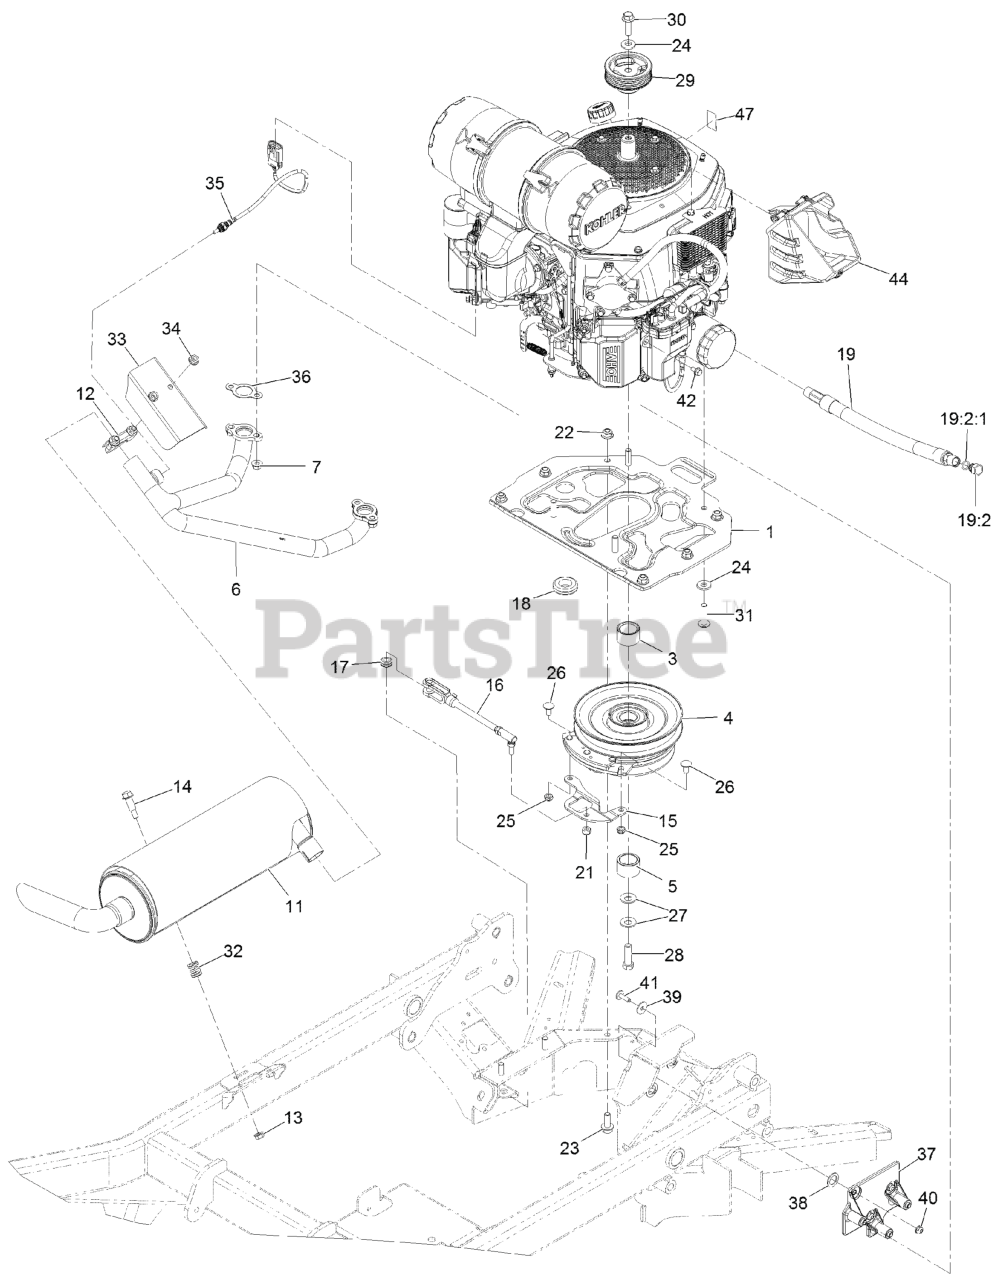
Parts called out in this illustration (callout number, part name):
1	PLATE, ENGINE
3	SPACER, CLUTCH
5	SPACER, CLUTCH
6	HEADER, KOHLER
7	NUT-FLANGE
12	CLAMP-MUFFLER
14	Bolt-Shoulder
15	STRAP, CLUTCH
16	ASM, CLUTCH ANCHOR
17	GROMMET
18	GROMMET
19	OIL DRAIN HOSE ASM
19:2	PLUG-HH
19:2:1	O-RING
21	NUT-LOCK
22	NUT-HF, NI
23	SCREW-HHF 3/8-16 X 1
24	WASHER-BELLEVILLE
25	NUT-LOCK, NI
26	SCREW-CARR
27	WASHER-SPRING
28	SCREW-HH 7/16-20 X 1 1/2 W/LOCTITE
29	PULLEY, CRANK
30	Screw-HH, Patch
31	SCREW-BHTF
32	SPRING, COMPRESSION
33	SHIELD, HEAT
35	SENSOR, MINI O2
36	GASKET-EXHAUST
37	Bracket-Pump, Fuel
38	Washer-Rubber
41	SCREW-TRUSS
42	SCREW-HHF
44	Duct Half, Rear
47	DECAL-10W-50 OIL
